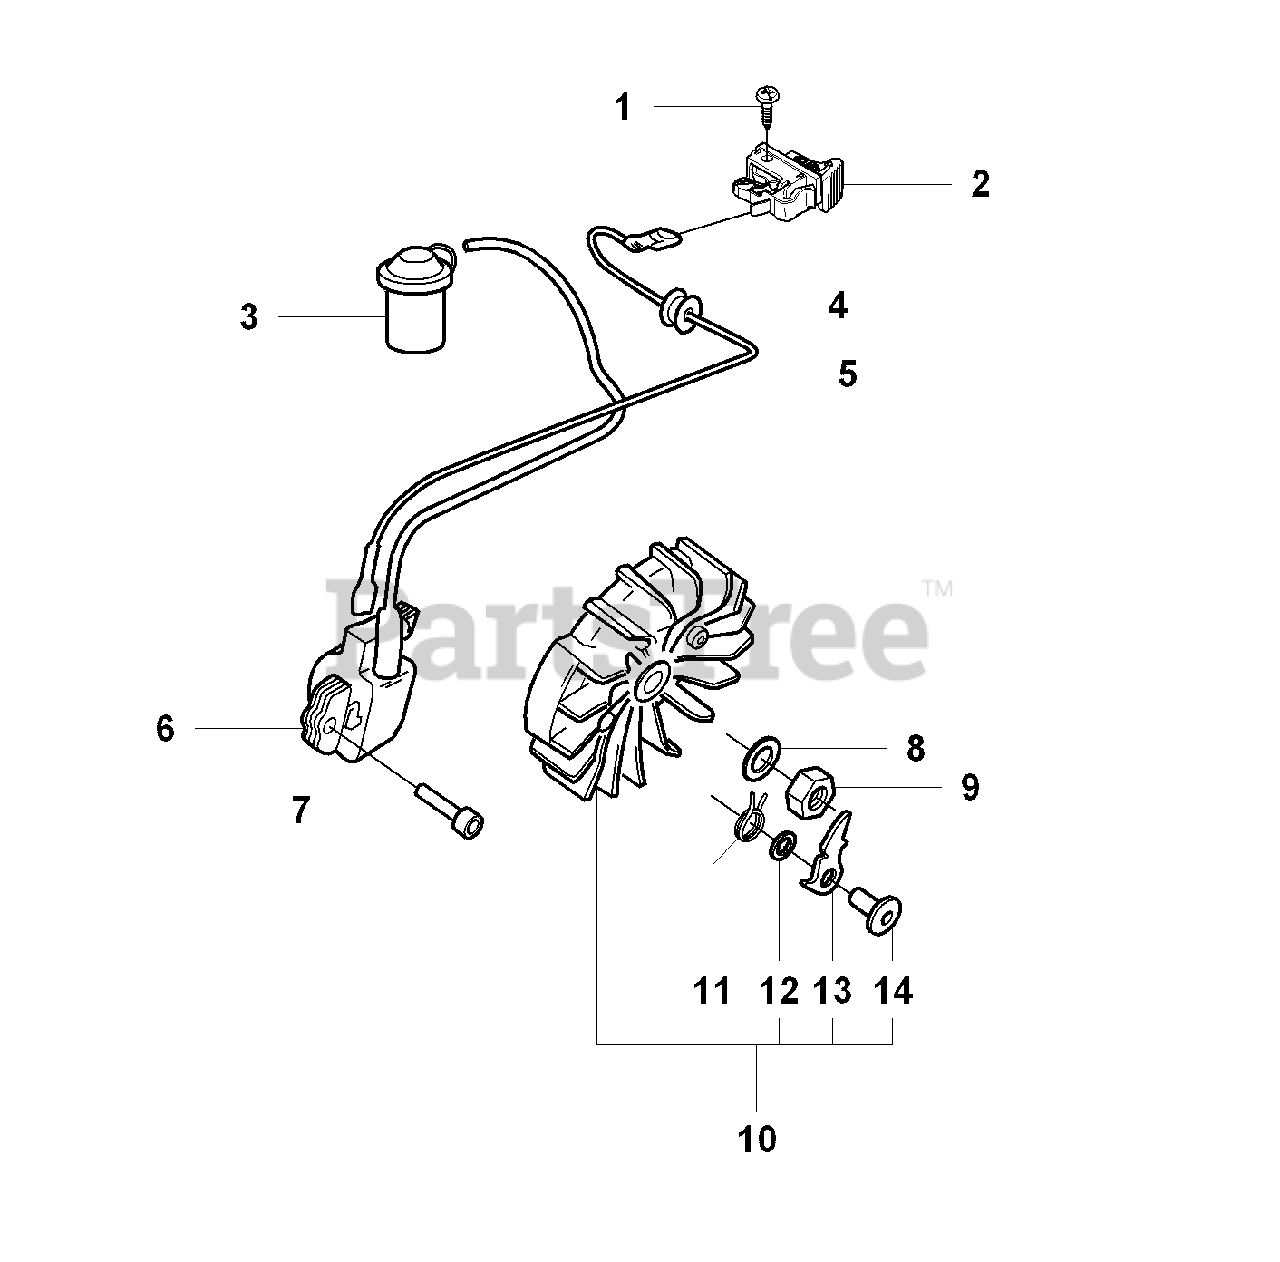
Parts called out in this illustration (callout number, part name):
1	SCREW
2	STOP SWITCH
3	SPARK PLUG CAP
4	CABLE GROMMET
6	IGNITION SYSTEM
8	SPRING WASHER
10	FLYWHEEL ASSY
12	WASHER STEEL
